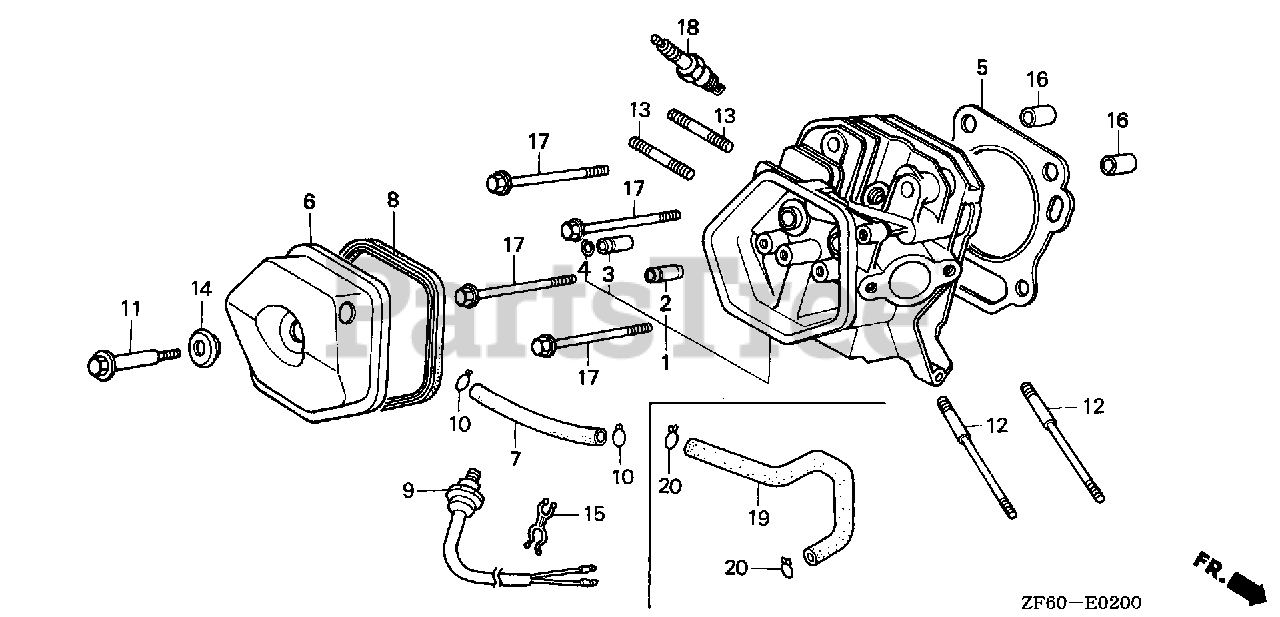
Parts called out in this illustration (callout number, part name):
1	CYLINDER HEAD
2	GUIDE, VALVE (OVER SIZE)
3	GUIDE, EX. VALVE (OVER SIZE)
4	CLIP, VALVE GUIDE
5	GASKET, CYLINDER HEAD
6	COVER, HEAD
7	TUBE, BREATHER
8	GASKET, HEAD COVER
11	BOLT, HEAD COVER
12	BOLT, STUD (8X106)
13	BOLT, STUD (8X32)
14	WASHER, HEAD COVER
16	PIN, DOWEL (12X20)
17	BOLT, FLANGE (10X80)
18	SPARK PLUG (BPR5ES) (NGK)
18	SPARK PLUG (W16EPR-U) (DENSO)
18	SPARK PLUG (BPR6ES) (NGK)
18	SPARK PLUG (W20EPR-U) (DENSO)
